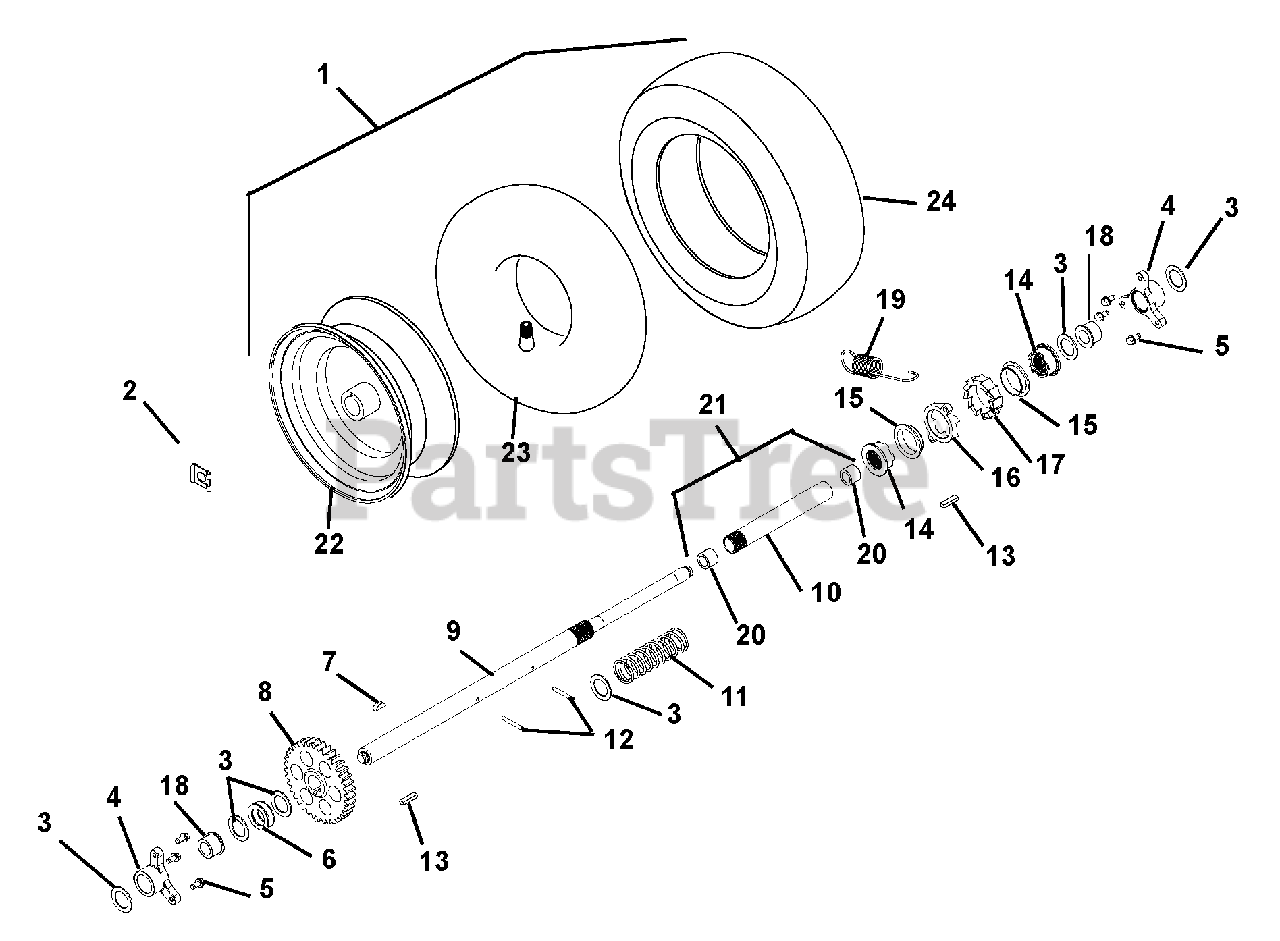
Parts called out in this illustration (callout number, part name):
1	TIRE/WHEEL,RH 15X5.00-6 REMOTE
2	CLIP, SNAP .625 DIA
3	WSHR-FL-STL 1.010X1.505X.062YZ
4	BUSHING, RAKE SHAFT 1"
5	@SCR-TAP .25-20X.50 HWH TR YWZ
6	SPACER 1.005X1.5075X.375
7	KEY-WDRF .25X.750X.313 SAE91
8	GEAR, SPUR
9	AXLE, DIFFERENTIAL-LONG
10	AXLE, DIFFERENTIAL-SHORT
11	SPRING, COMPRESSION
12	PIN-ROLL .188X1.50
13	KEY-RECT .25X.188X1.00
14	CLUTCH, DOG - SLIDING
15	BUSHING, FLANGE
16	GEAR, CLUTCH
17	GEAR, RATCHET
18	BSHG-FLG SPLIT NYLINER 1.0" HP
19	SG-TENS .06X.62X2.94
20	BSHG-SLV .706X.764X.75 BRZ
21	AXLE, DIFFERENTIAL-W/BUSHINGS
22	HUB, WHEEL - 15X5-6 REMOTE
23	TUBE 15 X 5.00-6
24	TIRE, X-TRAC 15X5-6
